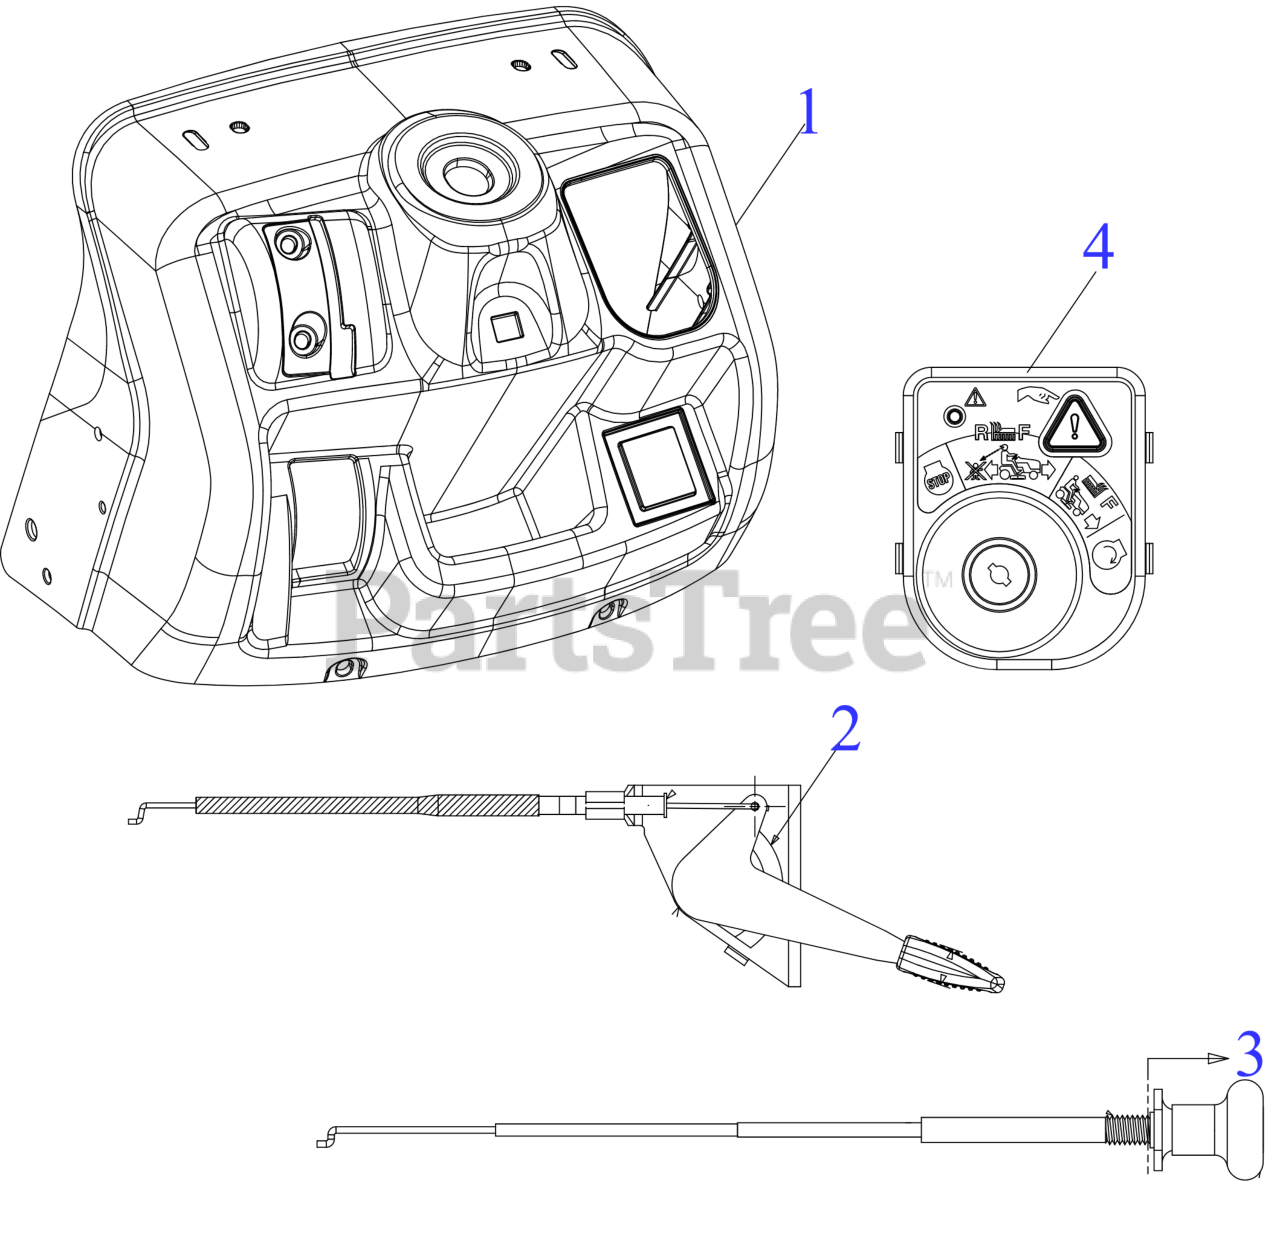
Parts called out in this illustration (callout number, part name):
1	UPPER DASH
2	THROTTLE CABLE 41.5 x .62
3	CHOKE CABLE 40.5 LG
4	IGNITION MODULE SWITCH RMC (MAN PTO BLK)
